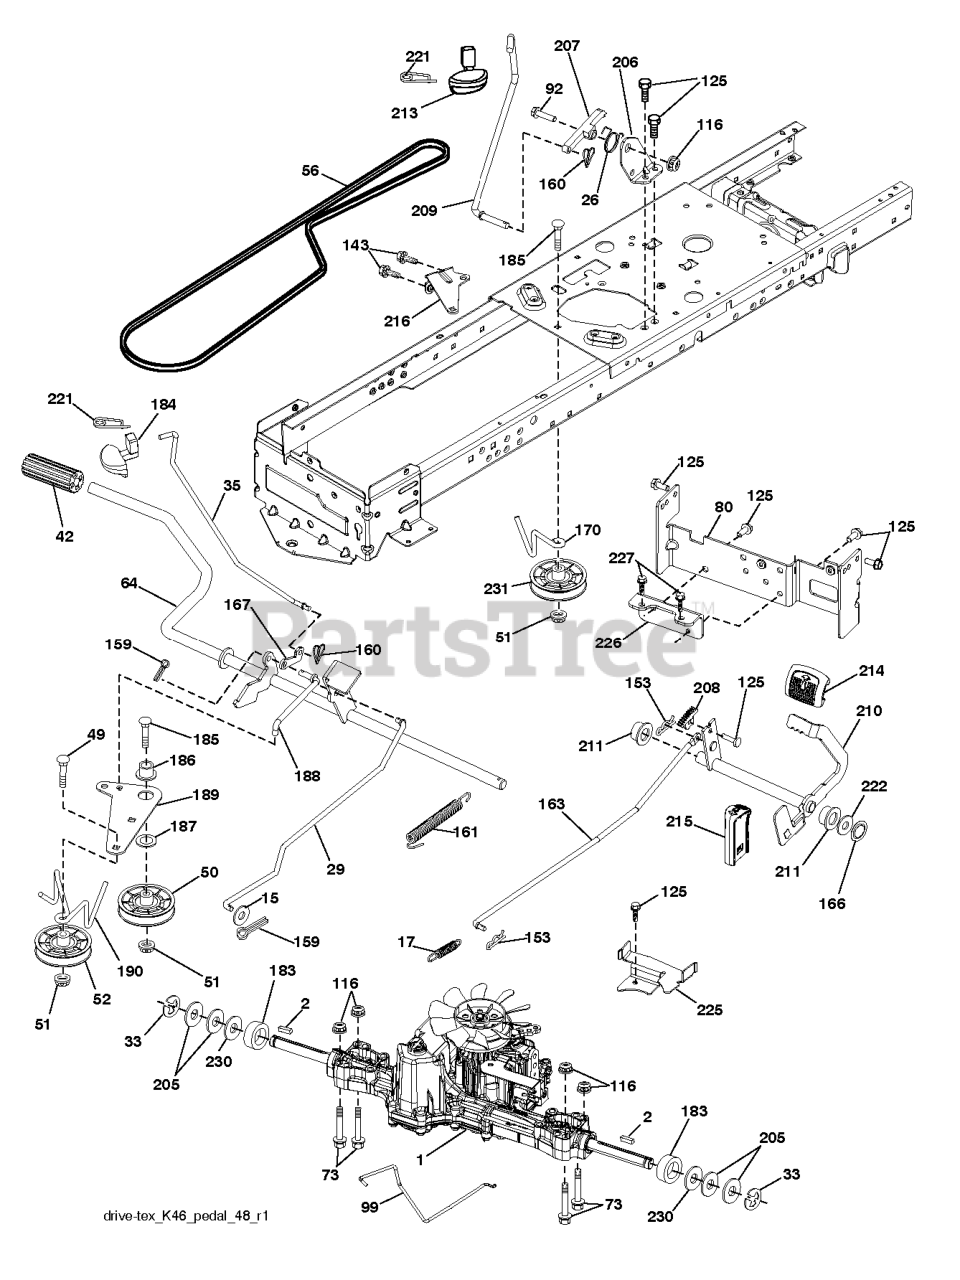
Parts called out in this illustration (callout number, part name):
1	TRANSAXLE(K46BT).PDL.
2	SQUARE KEY
15	WASHER
17	SPRING.BRAKE.K46.GREEN
26	SPRING.RETURN.CRUISE
29	ROD.BRAKE.K46
35	ROD.BRAKE.PARKING.GT.H
42	PEDAL COVER T
50	IDLER.FLAT.910.OFFSET
51	NUT LOCK FLG 3/8-16 UNC
52	IDLER.V-GROOVE.910.OFFSET
56	V-BELT.MOWER.92.40.42/K46
64	SHAFT.ASM.PEDAL.BRK.CNTR
73	BOLT HEX 5/16-18 GR 5
80	STRAP TORQUE
92	BOLT
99	ROD.SPRING.BYPASS.K46.LT.Z
116	NUT LOCK HEX FLANGE 5/16-18
125	SCREW
143	Screw 5/16-18 x 1/2 Hex, Self Tapping 5/16-18 x 1/2
153	RETAINER M
159	COTTER PIN
160	RETAINER CLIP
161	SPRING, RETURN LT
163	ROD.CONTROL.PEDAL.K46
166	NUT.PUSH.625
167	LATCH.BRAKE.SPRING
170	KEEPER.CENTER SPAN.1.688
183	SPACER AXLE
184	HANDLE.PARKG.BRK.HUSQ X667
186	SPACER.RETAINER
187	WASHER 12/32X2X10GA
188	RP.LINK.CLUTCH.GROUND.DRIVE
189	BELLCRANK.GROUND.DRIVE.TEX.
190	KEEPER.BELLCRANK.DRIVE
206	BRKT.MOUNT.LATCH.CRUIS
207	LATCH.CONTROL.CRUISE
208	GEAR.SECTOR.CONTROL.CR
209	ROD.CONTROL.CRUISE.GT.
210	ROCKER.ASM.PEDAL.CONTR
211	BEARING.NYLON
213	KNOB.CONTROL.CRUSIE.HU
214	PEDAL.FORWARD.PAD.TEX
215	PEDAL.REVERSE.TEX.GT.4
216	BRACKET.PULLEY.IDLER.W/TEX
221	RETAINER.SPRING.CLIP.H
222	WASHER 21/32 X 1-1/4 X 10 GA.
225	KEEPER.BELT.TRANSAXLE.K46
226	BRACKET.MOUNT.TORQUE.K46.TLT
227	SCREW.THDROL.5/16-18X3/4.TTY
230	WASHER.HARDENED
231	IDLER.V-GROOVE.1.688.OFFSET
